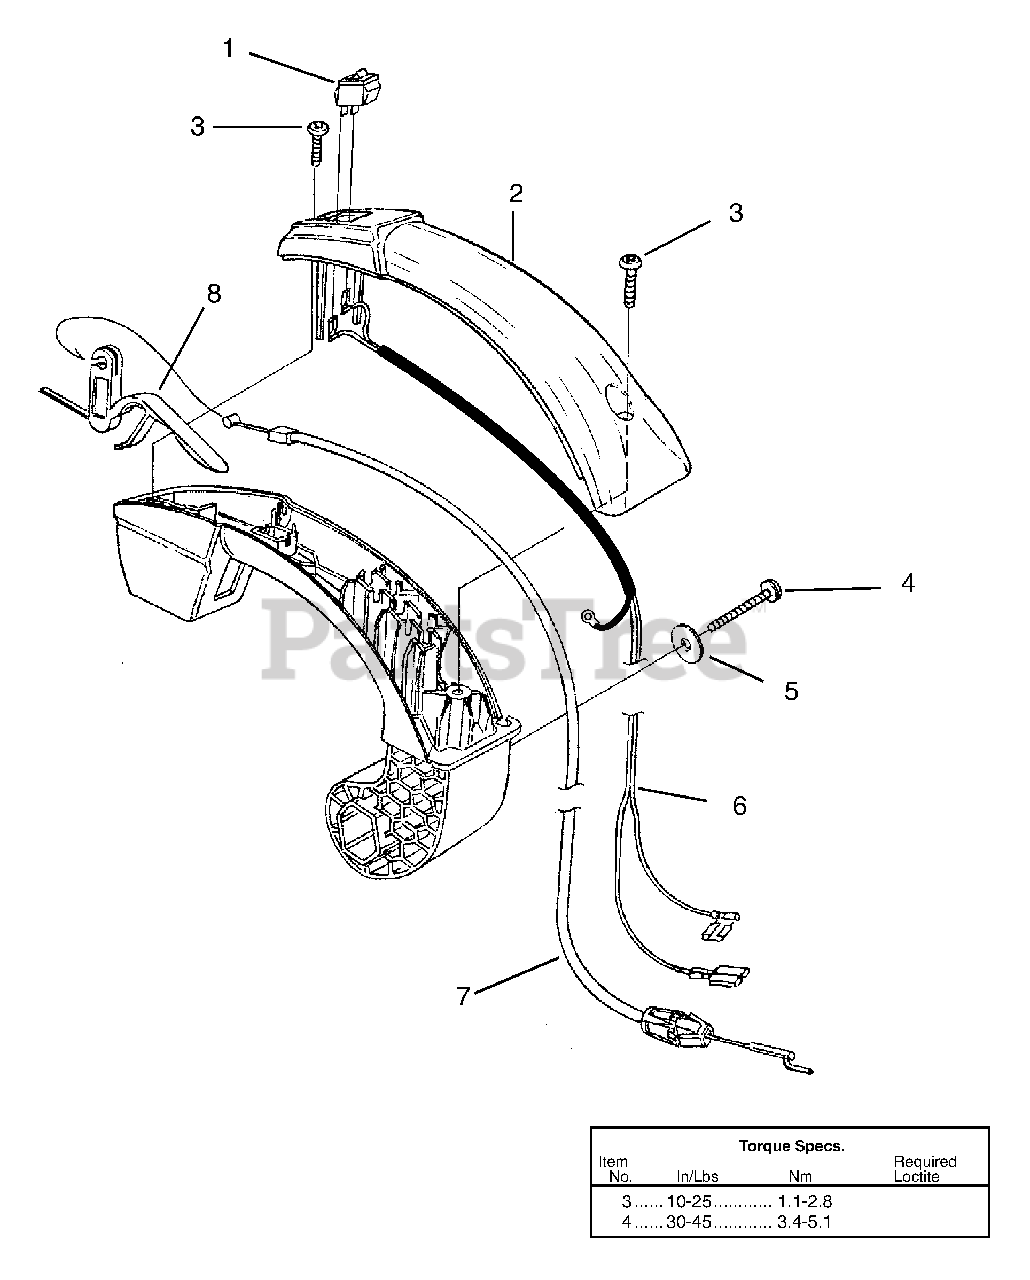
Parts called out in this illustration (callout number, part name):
1	Switch, Rocker (Stop)
2	Handle Cover
3	Screw, Thread Forming (8-16 X 1/2)
4	Screw, Thread Forming (10-14 X 7/8)
5	Washer, Flat
6	Kill Switch Leads
7	Cable, Throttle
8	Trigger
